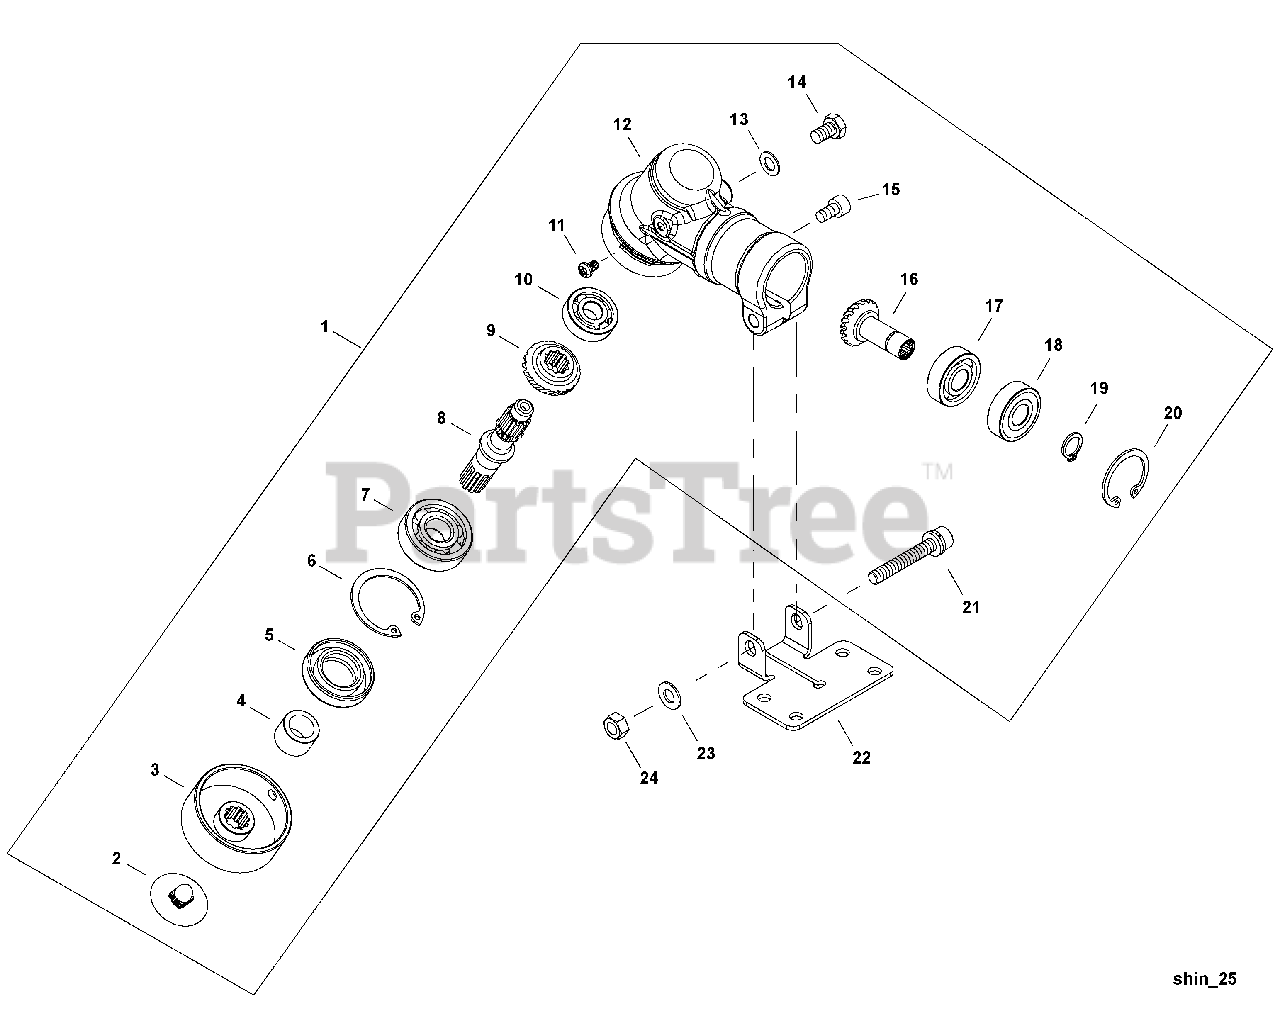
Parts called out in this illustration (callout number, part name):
1	GEAR CASE ASSY
3	ADAPTOR, BLADE - UPPER
4	COLLAR
5	SEAL, OIL
6	RING, RETAINING - 32
7	BEARING, BALL - 6201
8	GEAR - SHAFT
9	GEAR - BEVEL
10	BEARING, BALL - 609
11	SCREW - 4X6
12	CASE, GEAR
13	WASHER - 6
14	BOLT - 6X10
15	SCREW - 5X10
16	GEAR - BEVEL
17	BEARING, BALL - 6000
18	BEARING, BALL - 6000Z
19	RING, RETAINING - 10
20	RING, RETAINING - 26
21	SCREW - 6X40
22	MOUNTING PLATE, SHIELD
23	WASHER - 6
24	NUT - 6
